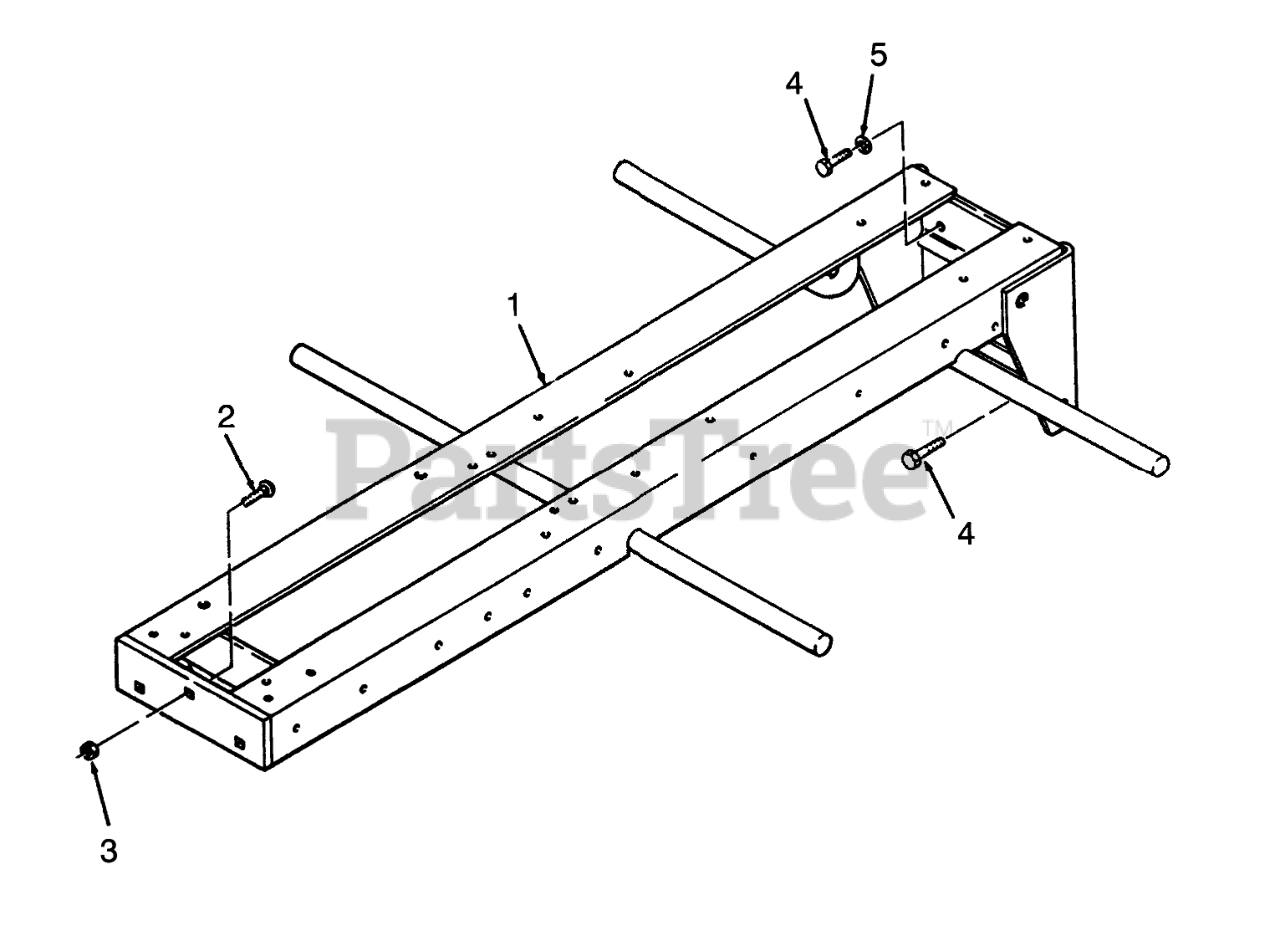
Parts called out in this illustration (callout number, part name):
2	BOLT-CARR
3	NUT-LOCK, NI
4	SCREW-HH
5	WASHER-LOCK
